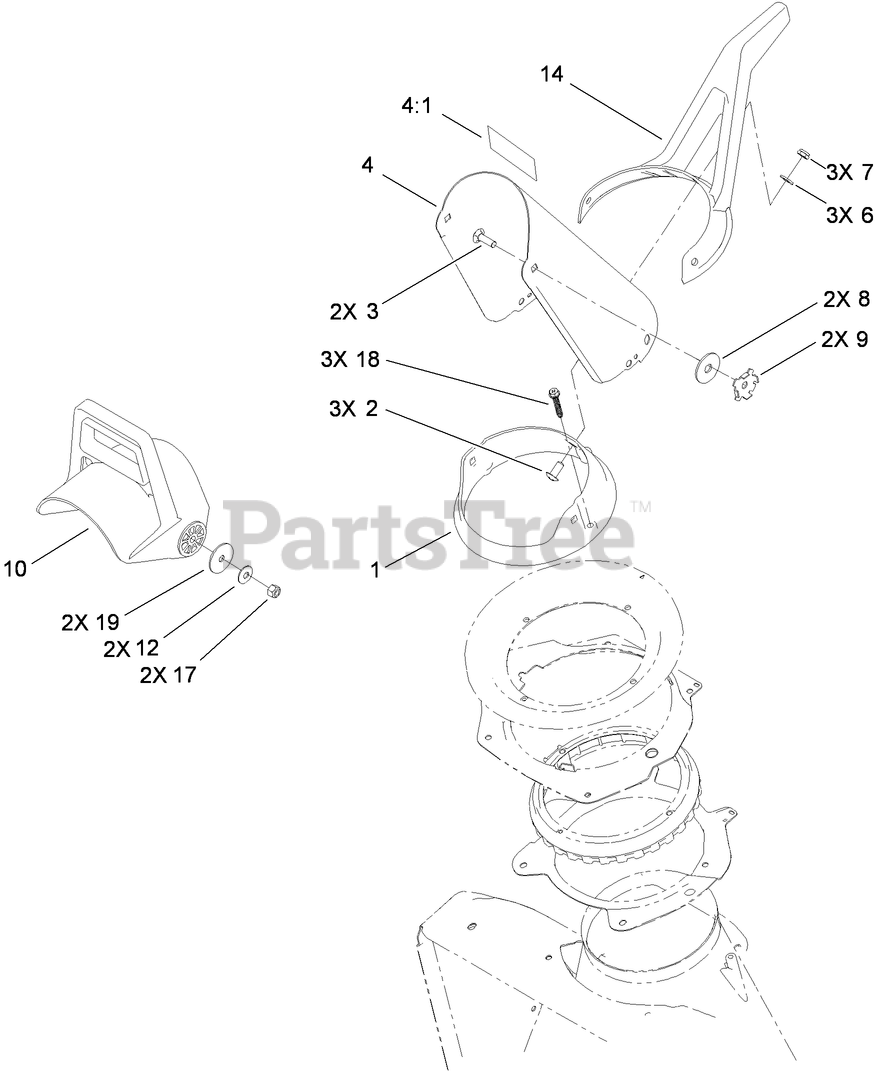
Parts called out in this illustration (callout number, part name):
1	RING-CHUTE
2	SCREW-PTH
3	SCREW-CARR
4	DISCHARGE CHUTE ASM
4:1	DECAL-DANGER, CE
6	WASHER-FLAT
7	NUT-LOCK, NI
8	WASHER-RUBBER
9	PLATE-FRICTION
10	CHUTE-DEFLECTOR
12	WASHER-BELLEVILLE
14	HANDLE-CONTROL, CHUTE
17	NUT-LOCK, NI
18	SCREW-PLASTITE
19	WASHER-FLAT
